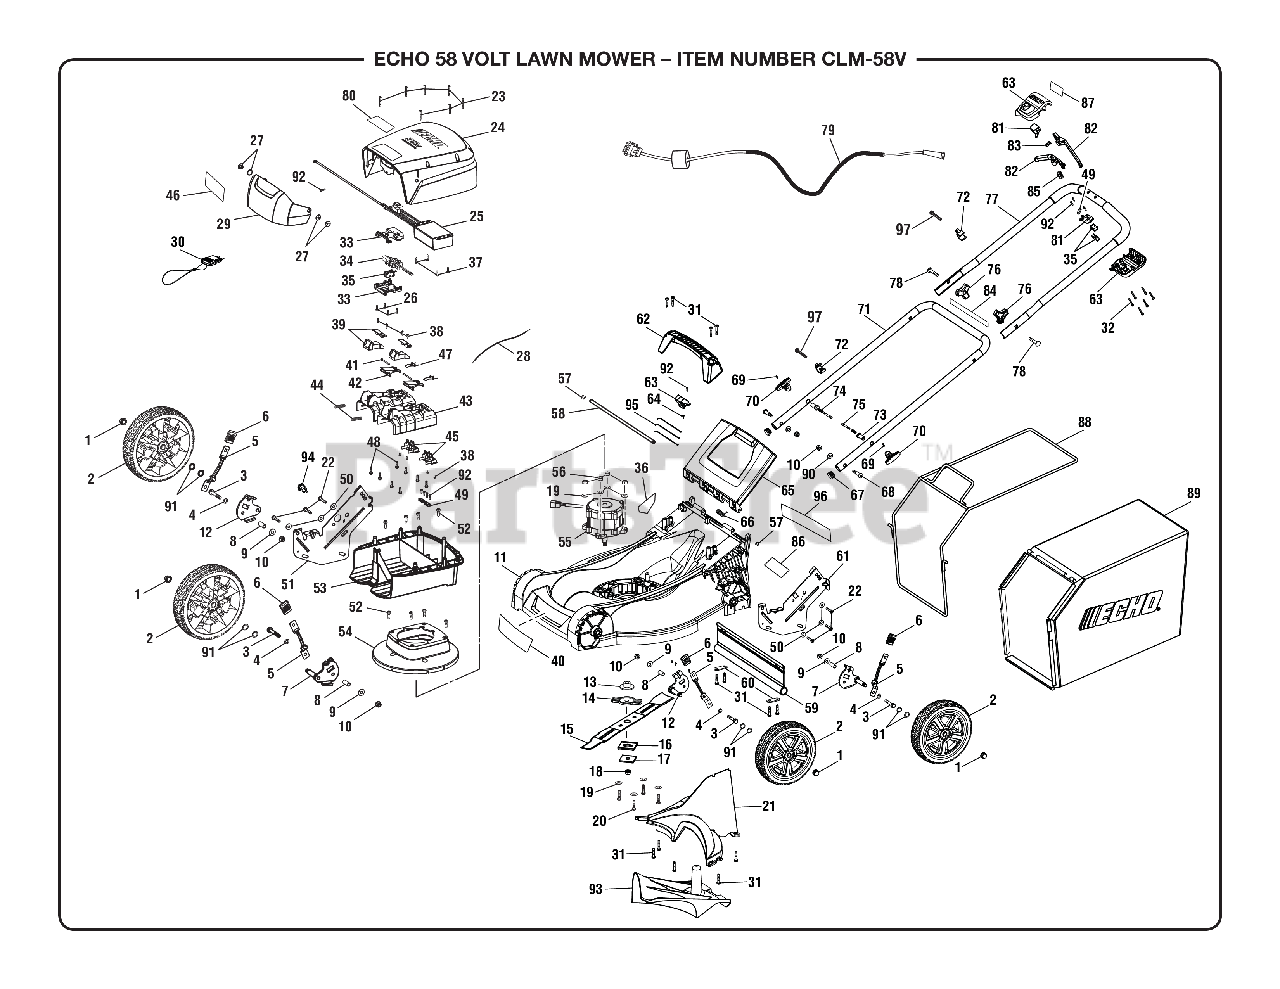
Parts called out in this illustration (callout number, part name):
1	Cap Nut
2	Wheel Assembly
3	Bolt (M8 x 50 mm)
4	Spring Washer (OD15 x ID8.4 x 0.8t)
5	Cutting Height Adjustment Lever
6	Height Adjustment Knob
7	Adjustment Axle Plate (Right Front and Left Rear)
8	Front Collar (Deck)
9	Washer (OD20.5 x ID8.5 x 2t)
10	Flange Nut (M8)
12	Adjustment Axle Plate (Right Rear and Left Front)
13	Bushing (Motor Axle)
14	Blade Holder
16	Spacer (Plastic)
17	Blade Retainer
18	Hex Nut (M10)
19	Washer (OD15 x ID6.2 x .08t)
20	Screw (M6 x 26 mm)
21	Discharge Baffle
22	Screw (1/4-15 x 17 mm, T30 Torx Pan Hd.)
23	Screw (M4 x 18 mm Torx Hd.)
24	Motor Cover (Upper)
25	Control Panel Assembly
26	Screw (M3.5 x 12 mm, Pan Hd.)
27	Rivet Assembly (Male and Female Set)
28	Lead Wire (185 mm, Yellow)
29	Battery Cover (Upper Lid)
30	Start Key Assembly
31	Screw (1/4-15 x 1-1/4 in., T30 Torx Pan Hd.)
32	Screw (M4 x 30 mm)
33	Key Housing Assembly
34	Pin Socket Assembly
35	Switch (On/Off)
36	No Hands or Feet Label/CPSC Label
37	Screw (M4 x 16 mm)
38	Screw (M3 x 12 mm, Pan Hd.)
39	Battery Release Button and Retainer Assembly
40	Front Cover Label
41	Battery Latch
42	Battery Release Latch
43	Battery Carriage
44	Compression Spring
45	Battery Contact Assembly
46	Logo Label
47	Torsion Spring
48	Screw (M5 x 17.5 mm, T20 Torx Pan Hd.)
49	Cord Clamp
50	Washer (1/4 in.)
51	Handle Adjustment Mount (Right)
52	Screw (1/4-15 x 3/4 in., T30 Torx Pan Hd.)
53	Motor Cover (Center)
54	Motor Cover (Lower)
56	Hex Nut (M6)
58	Axle (Rear Door)
59	REAR GUARD
60	Bracket (Rear Guard)
61	Handle Adjustment Mount (Left)
62	Deck Handle
63	Switch Cover and Housing Assembly
64	Screw (M3 x 12 mm, Pan Hd.)
65	Rear Door
66	Compression Spring (Rear Door)
67	End Cap
68	Screw (M8.0 x 18 mm, T40 Torx Hd.)
69	Spring Pin (11 mm)
70	Spring Pin Adjustment Knob
71	LOWER HANDLE
72	Cord Clamp
73	Spring Pin (Housing)
74	Compression Spring
75	Detent Pin
76	Wing Nut w/Insert
77	Upper Handle Assembly
78	Screw (M8 x 57 mm)
79	Wire Assembly
80	Start Key Warning Label
81	Spring Holder and Button Assembly
82	Trigger Assembly
84	"Power-Adapt" Label
85	Compression Spring
86	Data Label
87	Quick Start Label
88	Frame (Grass Bag)
89	Grass Bag Assembly
90	Washer (ID8.5 x OD20.5 x 3t)
91	Wavy Washer (ID13.7 x OD19.2)
92	Screw (M4 x 13.5 mm, T15 Torx Pan Hd.)
93	Mulching Plug
94	Switch (Serial Number Before EU18131, 3.26.18)
95	Cable Tie
96	Warning Icon Label
97	Screw (M3 x 20 mm)
